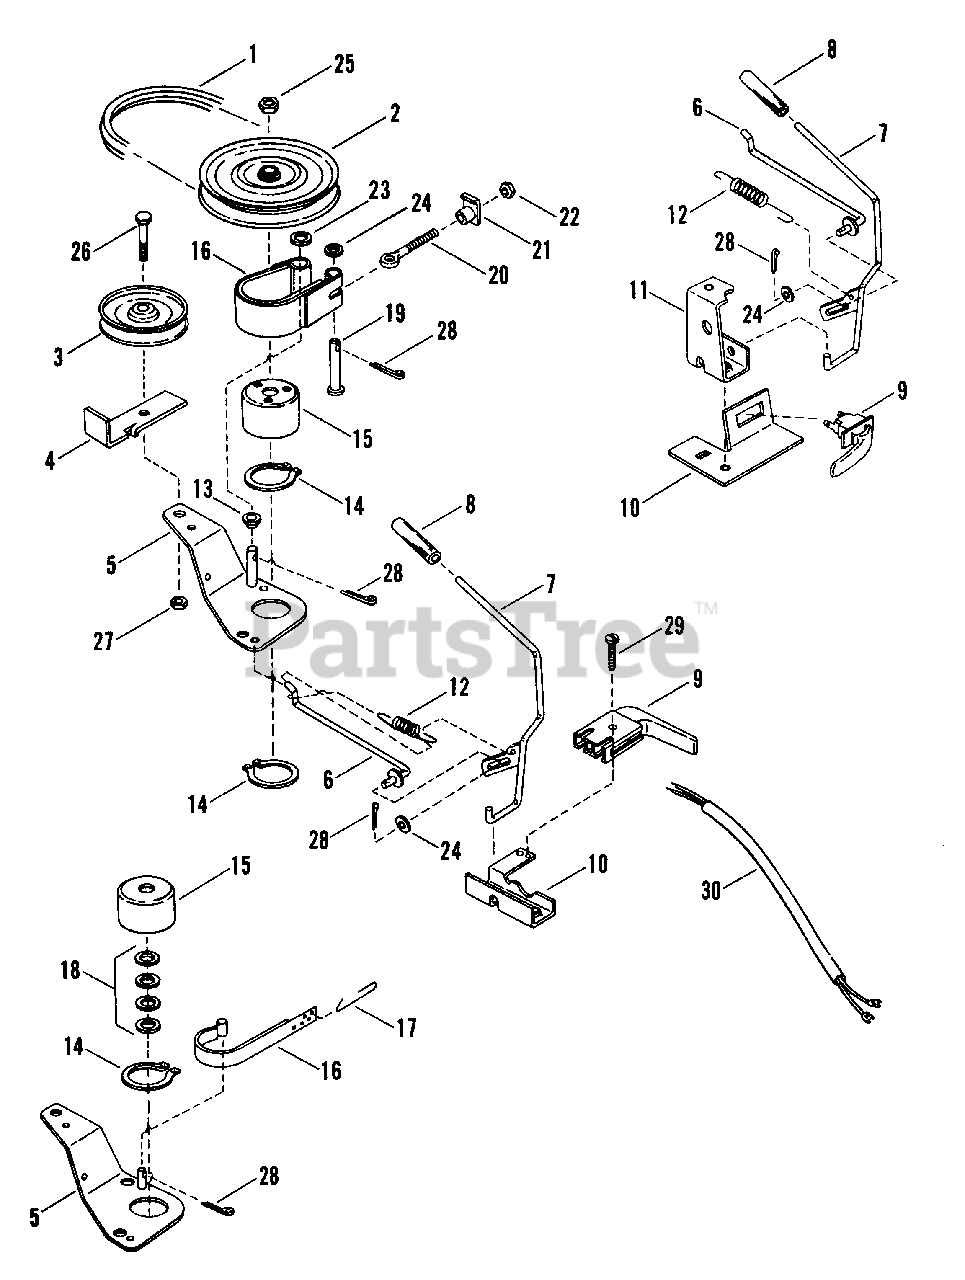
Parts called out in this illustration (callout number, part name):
1	BELT, Drive AA68
2	PULLEY, Spindle (Note: Also use 15290)
3	PULLEY, Idler
4	RESTRICTOR, Belt
5	ARM, Idler
6	ROD, Idler
7	HANDLE, Blade ON-OFF (Lever)
8	GRIP, Handle
9	SWITCH, Deck Interlock
10	MOUNT, Handle
11	ADAPTER, Handle Mount
12	SPRING, Blade Handle
13	SPACER
14	RING, 2" External Retaining
15	DRUM, Brake
16	BAND, Brake
17	LINK, Wire
18	WASHER, Spacer
19	PIN, 1/4 Clevis
20	EYE-BOLT
21	TEE-NUT
22	NUT, 1/4 Hex
23	WASHER, 3/8 SAE
24	WASHER, 1/4 SAE
25	NUT, 3/4-16 Hex Jam
26	CAPSCREW, 3/8-24x1-3/4 Hex Head
27	LOCKNUT, 3/8-24
28	COTTER-PIN, 3/32x3/4
29	SCREW, No. 10x1, Self Tap
30	HARNESS, Deck Interlock Wiring
